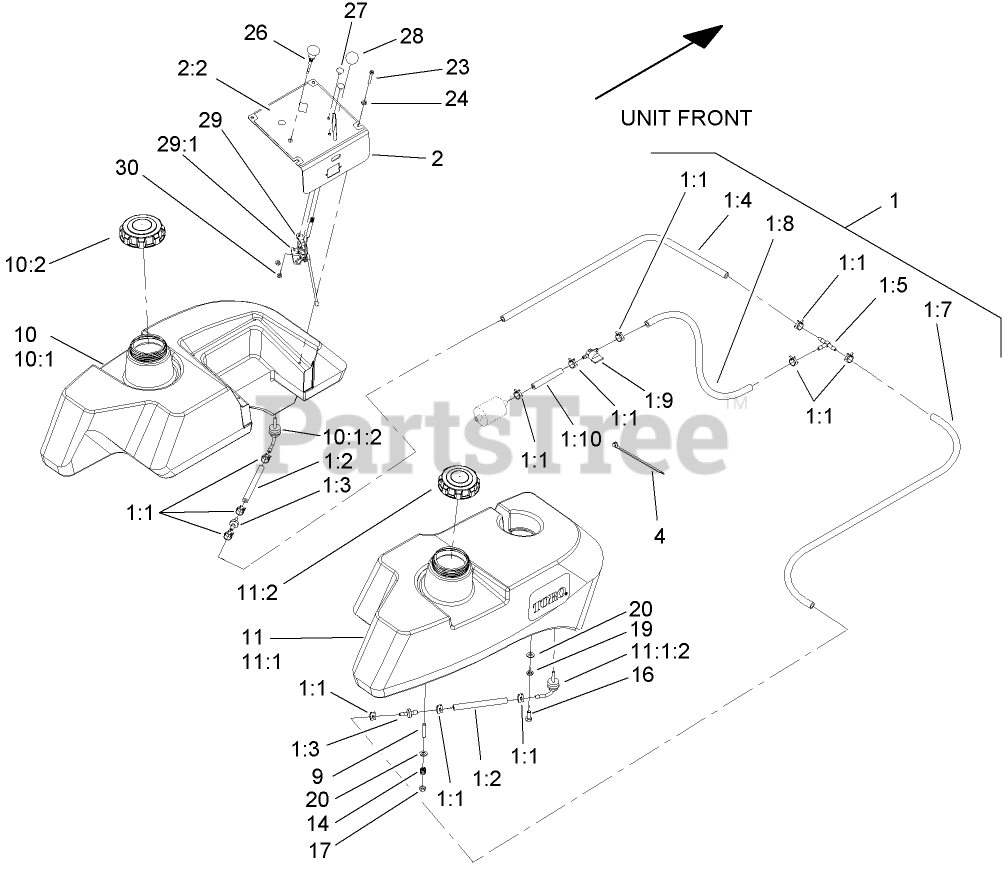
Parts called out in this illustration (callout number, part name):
1	FUEL LINE ASM
1:2	HOSE-FUEL
1:3	VALVE-CHECK, FUEL
1:4	HOSE-FUEL
1:5	FITTING-TEE, BARBED
1:7	HOSE-FUEL
1:8	HOSE-FUEL
1:9	VALVE-FUEL
1:10	HOSE-FUEL
2	CONTROL PANEL ASM
2:2	DECAL-PANEL, CONTROL
4	TIE-PLASTIC
10	LH FUEL TANK KIT
10:1	LH FUEL TANK ASM
10:1:2	FITTING-FUEL, BULKHEAD
10:2	CAP-FUEL, GAS
11	RH FUEL TANK KIT
11:1	RH FUEL TANK ASM
11:1:2	FITTING-FUEL, BULKHEAD
11:2	CAP-FUEL, GAS
14	SPRING-TANK, FUEL
16	SCREW-HH
17	NUT-LOCK, NI
19	WASHER-LOCK
20	WASHER-PLAIN
23	SCREW-PPH
26	Control-Choke, Push / Pull
27	BOLT-CARR
28	KNOB-BALL
29	CABLE-THROTTLE
29:1	LEVER-THROTTLE
30	NUT-LOCK, NI
